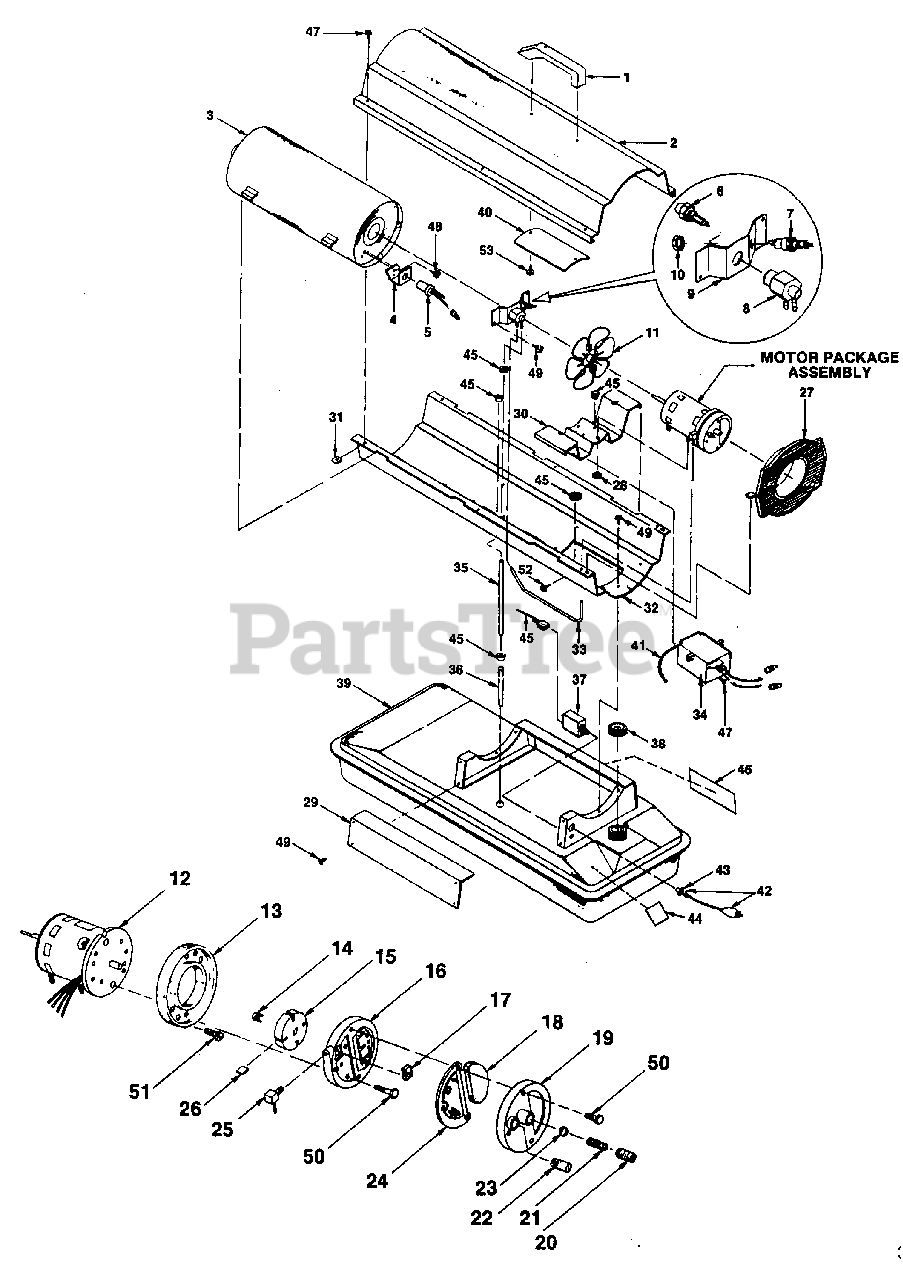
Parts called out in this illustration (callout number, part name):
2	UPPER SHELL
3	COMBUSTION CHAMBER (HH35)
4	BRACKET- Photocell
5	PHOTOCELL ASSEMBLY
6	NOZZLE (HH35)
7	SPARK PLUG
8	ADAPTER- Nozzle
10	NUT- 14mm
13	BODY- Pump
16	COVER- End pump
17	FILTER- Lint
18	FILTER- Intake
19	FILTER- End cover
20	SCREW- Adjusting
21	SPRING- Pressure relief
23	BALL- Steel 1/4" dia.
24	FILTER- Output
25	ELBOW- 90
27	FAN GUARD
28	NUT- Hex lock
29	COVER- Side
30	BRACKET- Motor
31	NUT- Clip
32	SHELL- Lower
33	RUBBER AIRLINE
35	FUEL LINE (HH35)
36	FUEL FILER ASSY. (HH35)
37	SAFETY CONTROL
38	FUEL CAP (Incudes gasket)
39	FUEL TANK
40	HEAT-SHELL SHIELD
41	IGNITOR CABLE ASSEMBLY
42	POWER CORD ASSY.
43	BUSHING- Strain relief
44	DECAL- Warning
45	RUBBER BUSHING & BUMPER KIT
46	DECAL- General Info. (HH35)
